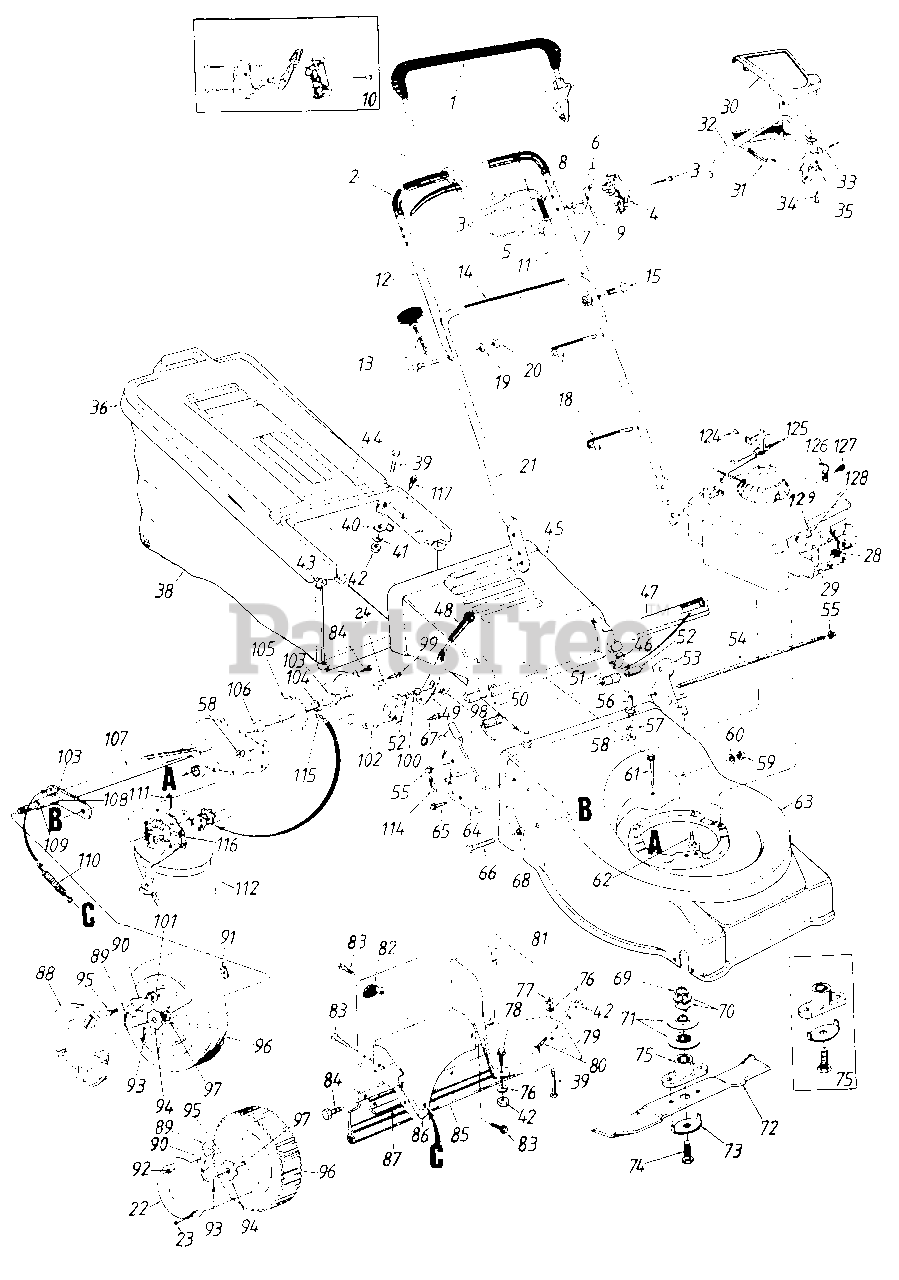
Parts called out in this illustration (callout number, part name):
1	Control Handle Ass'y.
2	Grip
3	Truss Mach. B-Tap Scr. #12 x 1.5" Lg.
4	Control Panel Half
5	Clutch Panel Half
6	Throttle Control Lever
7	Control Disc Pin
8	Control Label-Throttle
9	Throttle Wire-58" Lg.
10	Control Housing Comp.
11	Control Cable-43" Lg.
12	Upper Handle
13	Rope Guide Bolt
14	Instruction Label-Handle
15	Curved Carriage Bolt 5/16-18 x 1.38" Lg.
18	Cable Tie
19	L-Wash. 5/16" I.D.
20	Hex Nut 5/16-18 Thd.
21	Lower Handle
23	Pan HD. Tap Scr. #12 x .50" Lg.
24	Bell-Wash. .265" I.D. x .75"
28	Spark Plug Boot
29	Engine
30	Control Cover Half-Upper
31	Control Cover Half-Lower
32	Control Lever
33	Drive Cable-53" Lg.
34	Flat C-Sunk Hd. Tap Scr. #10 x .75" Lg.
35	Cable Mtg. Cap
36	Hardtop Bag Cover
38	Grass Bag
39	Truss Mach. Scr. 1/4-20 x 1.0" Lg.
40	Mounting Clamp
41	Fl-Wash. .281" I.D. x .62"
42	Hex Nut 1/4-20 Thd.
43	Front Catcher Frame
44	Rear Catcher Frame
45	Chute Deflector
46	Deflector Plug
47	Seal-Extrusion
49	Spring Lever
50	Torsion Spring-R.H.
51	Torsion Spring-L.H.
52	Spacer.255" I.D.
53	Handle Brkt. Ass'y.-L.H.
54	Hinge Pin 17.75" Lg.
55	Cap Speed Nut
56	Shld. Pin 3/8-24 x 1.43" Lg.
57	L-Wash. 3/8" I.D.
58	Hex Jam Nut 3/8-24 Thd
59	Hex L-Nut 3/8-24 Thd.
60	Bell-Wash. .38" I.D. x .88"
61	Hex Wash. Hd. Tap Scr. 1/4-20 x 1.5" Lg.
62	Hex L-Wash. Hd. Scr. 3/8-16 x 1" Lg.
63	21" Deck Ass'y.
64	Handle Brkt. Ass'y.-R.H.
65	Hex L-Wash. Hd. AB-Tap Scr. 1/4 x.62" Lg.
66	Hex Wash. Hd. Tap Scr. 3/8-16 x .75" Lg.
67	Hex Wash. Hd. Tap Scr. 1/4-20 x .5" Lg.
68	Spacer.385" I.D.
69	Serrated Washer 1.0" I.D.
70	Wave Washer 1.005" I.D.
71	Serrated Pulley Half
72	21" Blade
73	Blade Bell-Wash. .44" I.D.
74	Hex Bolt 7/16-20 x 1.5" Lg. (Gr. 5)
75	Blade Adapter Kit
76	L-Wash. 1/4" I.D.
77	Hex Jam Nut 1/4-20 Thd.
78	Hex Bolt 1/4-20 x .85" Lg.
79	Rear Belt Baffle
80	Carr. Bolt 1/4-20 x .50" Lg.
83	Torx Mach. AB-Tap Scr. 1/4 x .62" Lg.
84	Hex B-Tap Scr. 1/4 x .38" Lg.
85	Rear Flap
89	Plastic Spring
90	Pawl.345" I.D.
91	Weld Nut 1/4-2Q Thd.
92	Hex Ins. L-Nut 1/4-20 Thd.
93	Cotter Pin 1/8" Dia.
94	Ratchet Wheel 1.62" O.D.
95	Shld. Bolt .342" Dia. x .268"
96	Wheel Ass'y. Comp.-Rear
97	Flange Ball Bearing 1/2" I.D.
98	Shld. SPacer.5o Dia.
99	Hex Bolt 1/4-20 x .62" Lg. (Gr. 5)
100	Shld. Pin 3/8-24 x 1.43" Lg.
101	Bell-Wash. .265" I.D. x .75"
102	Chain Cover Ass'y.
103	Hex Flange Brg. .506" I.D.
104	Fl-Wash. .531n l.D. x .93"
105	Rear Axle Ass'y.
106	Hex Flange Bearing
109	Spacer.513" I.D.
110	Extension Spring 3.8" Lg.
111	Spacer.325" I.D.
112	V-Belt
114	Internal Cotter Pin 5/16" Dia.
115	#48 Chain .50" Pitch x 30 Links
116	Transmission Comp.
117	Hex AB-Tap Scr. 1/4 x .62" Lg.
124	Pop Rivet .156" Dia.
125	Cable Brkt.
126	Cable Clamp
127	Hex B-Tap Scr. #10 x .38" Lg.
128	Hex B-Tap Scr. #10 x .62" Lg.
